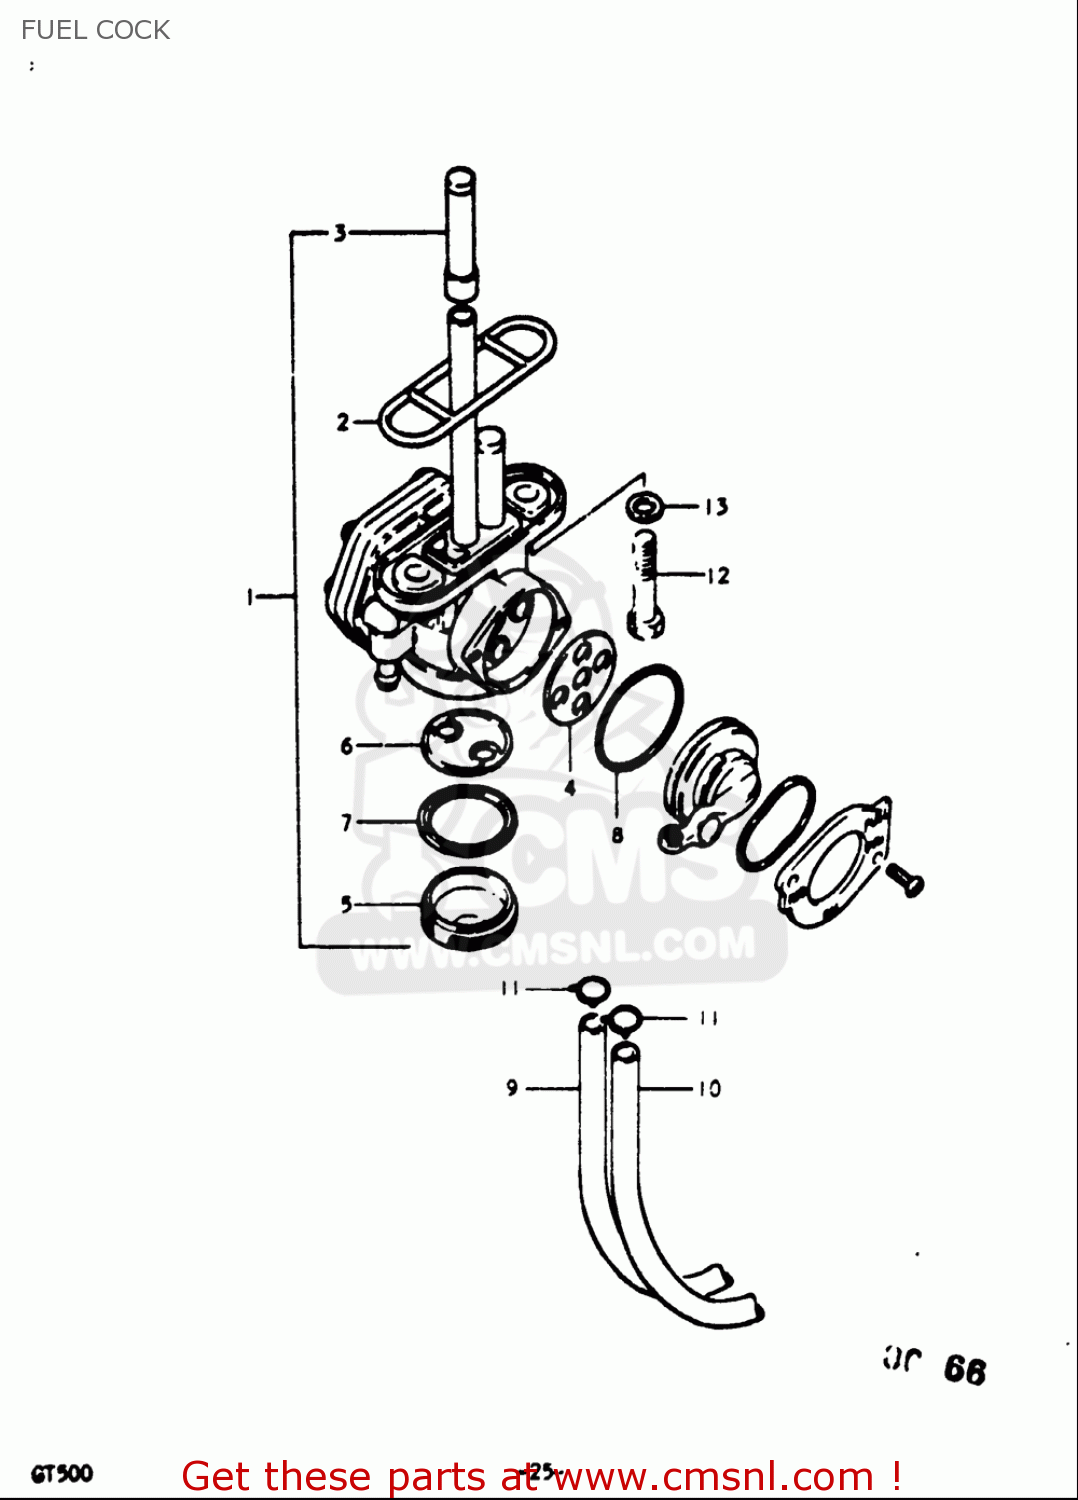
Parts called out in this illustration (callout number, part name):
2	GASKET, FUEL COCK (NAS)
3	FILTER
4	GASKET (NAS)
6	FILTER,CUP
7	GASKET,CUP (NAS)
8	V SEAL,FUEL COCK
9	HOSE(5X8.2X600)
10	HOSE(5X9X600)
11	CLIP
12	BOLT(6X20)
13	GASKET(5.8X13X1.2) (NAS)
